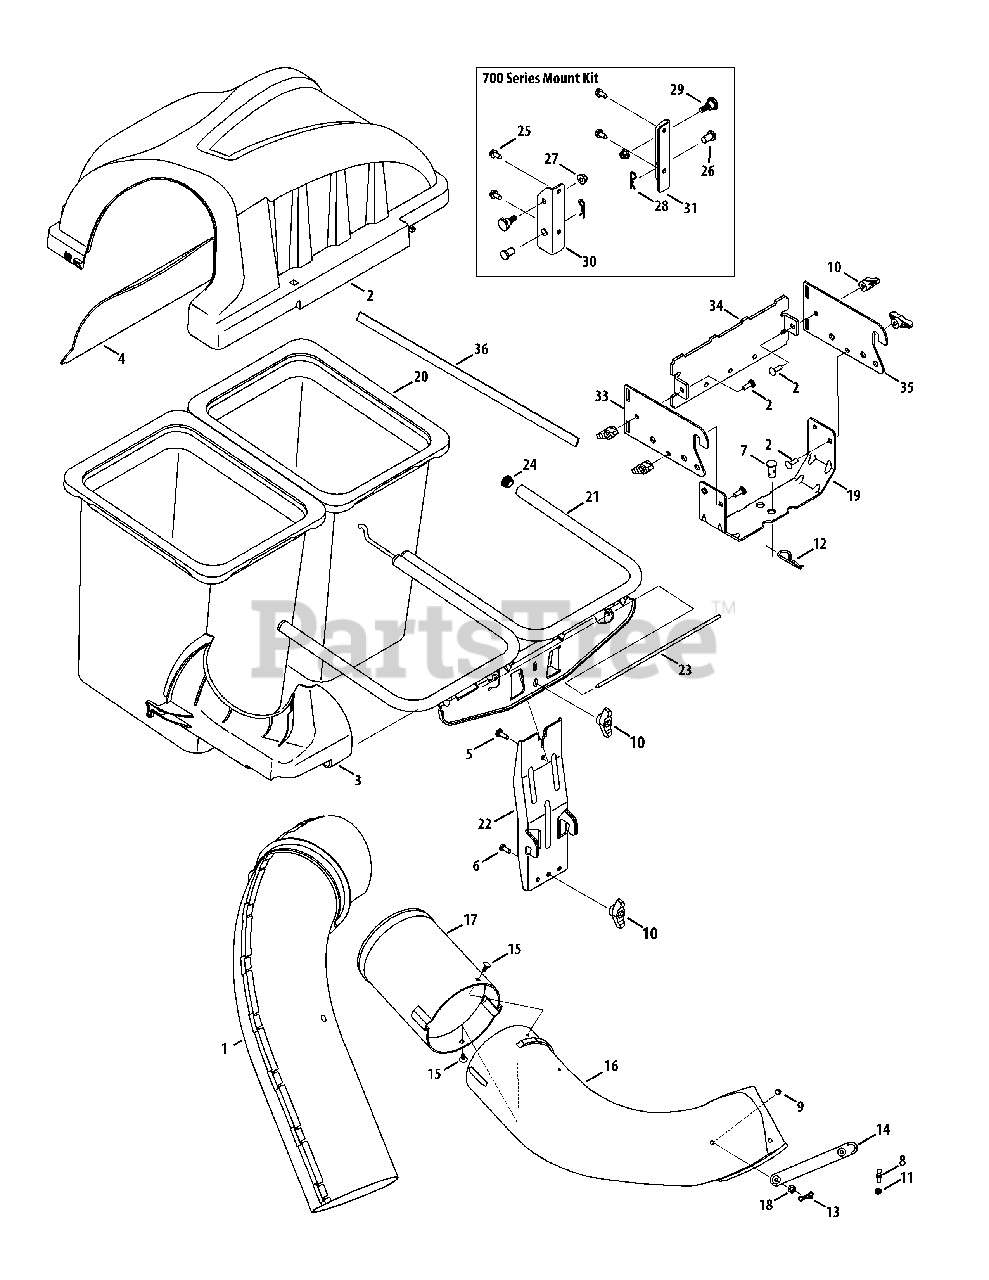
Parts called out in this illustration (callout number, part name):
1	Upper Chute Assembly
2	Double Bagger Cover Assembly
3	Upper Chute Support
4	Bagger Cover Screen
5	Carriage Screw, 5/16-18 x 1.00"
6	Hex Head Screw, 5/16-18 x .75"
7	Clevis Pin, .62" Dia.
8	Grass-catcher Pin, 1/4-20
9	Clevis Pin, 5/16 x .75 Lg.
10	Wing Knob
11	Flange Lock Nut, 1/4-20
12	Internal Cotter Pin, .148 x 3.00
13	Bow-Tie Cotter Pin, 72
14	Chute Strap, 6.00 Lg.
15	Ratchet Clip, .250
16	Discharge Chute Elbow, 38"/42" Deck
17	Bagger Chute Adapter, 8 In.
18	Flat Washer, .344 x .62 x .033
20	Grass-bag Assembly
23	Cover Hinge Pin
24	End Plug
25	Tap Screw, 5/16-18 x .750
26	Clevis Pin, .50 x .78 Lg.
27	Flange Lock Nut, 3/8-16
28	Click Pin, .092 x 1.64 Lg.
29	Shoulder Screw, .625 x .412
33	Hitch Bracket, RH
34	Rear Attachment Bracket
35	Hitch Bracket, LH
36	Self-Adhesive Foam Strip
